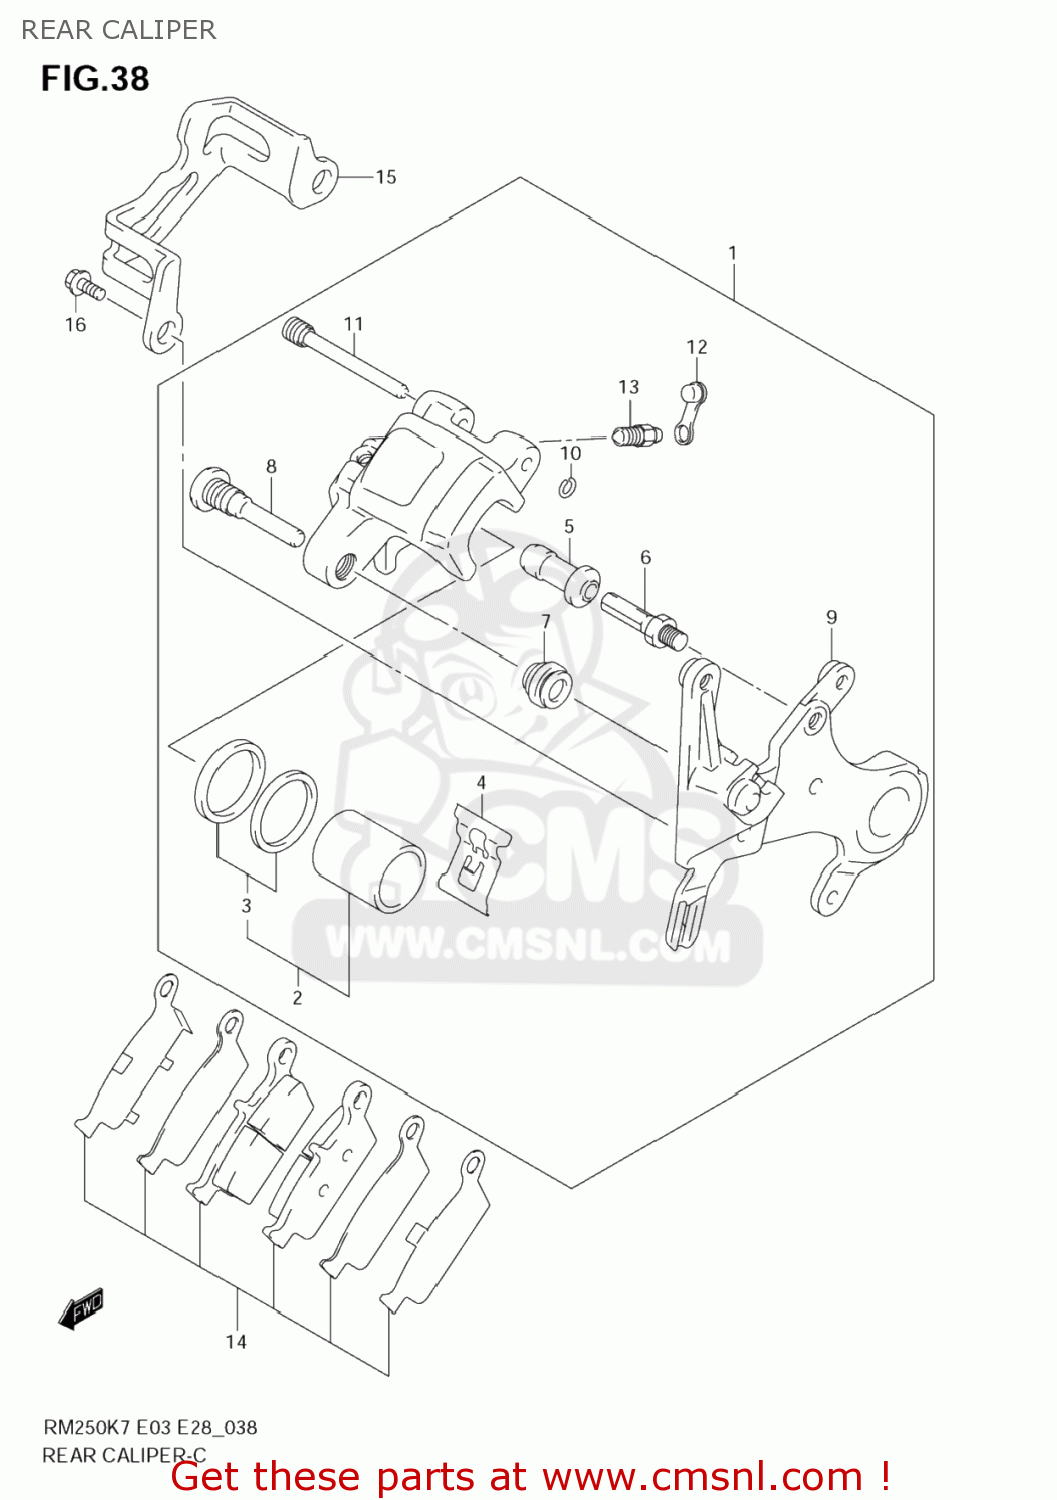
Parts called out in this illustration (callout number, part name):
1	CALIPER ASSY,RR
2	PISTON SET
3	SEAL SET,PISTON
4	SPRING,PAD
5	BOOT
6	PIN,BOLT
7	BOOT
8	PIN,BOLT
9	BRACKET
10	RING,STOPPER
11	PIN,HANGER
12	BLEEDER
13	CAP,BLEEDER
14	PAD & SHIM SET (NAS)
15	GUARD,RR CALIP
16	BOLT(6X12)
